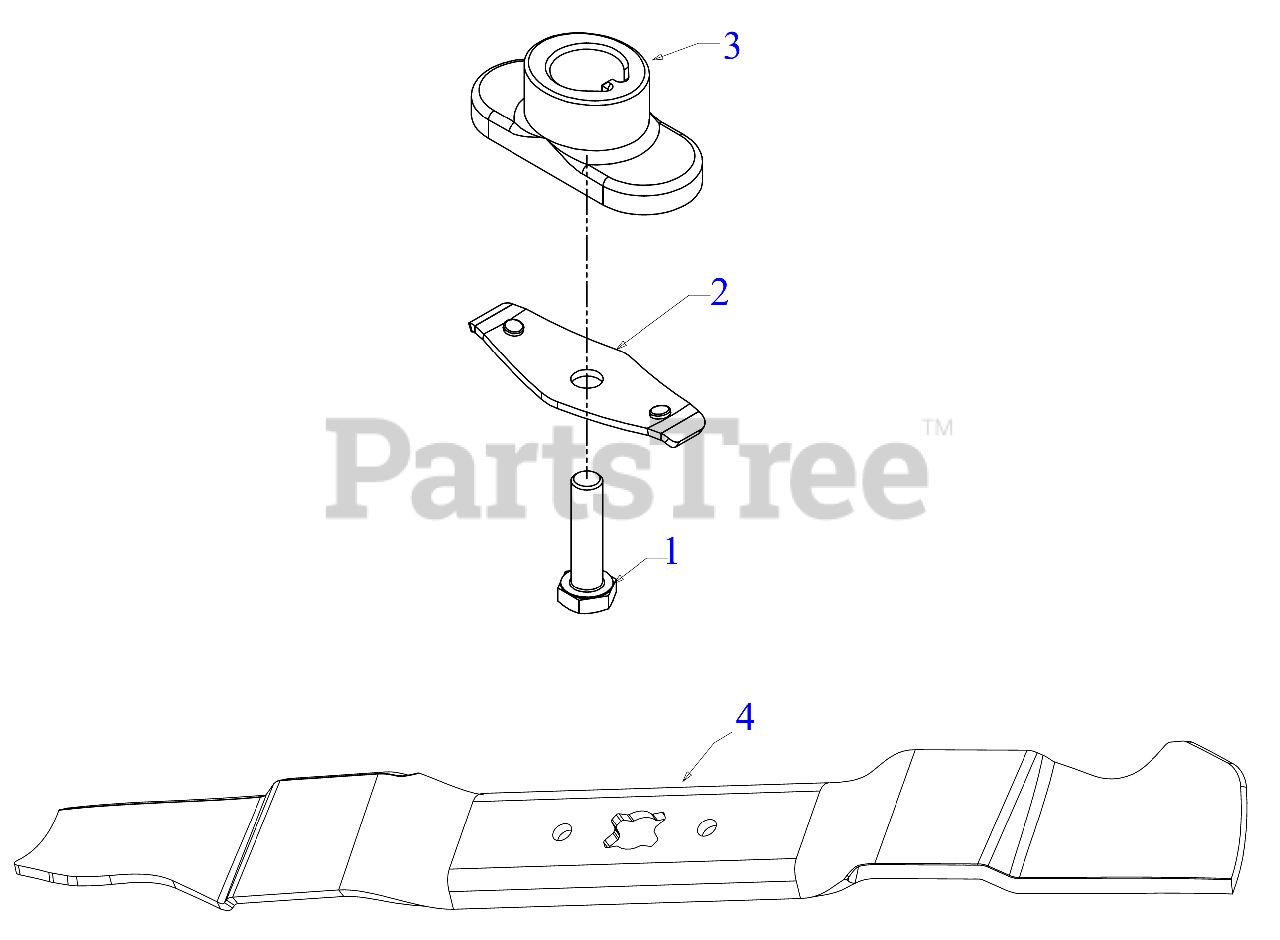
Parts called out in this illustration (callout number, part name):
1	SCREW 3/8-24 x 1.50 GR8
2	BLADE BELL SUPPORT
3	BLADE ADAPTER-W/STAR
4	21" MULCHING BLADE (2-IN-1)
